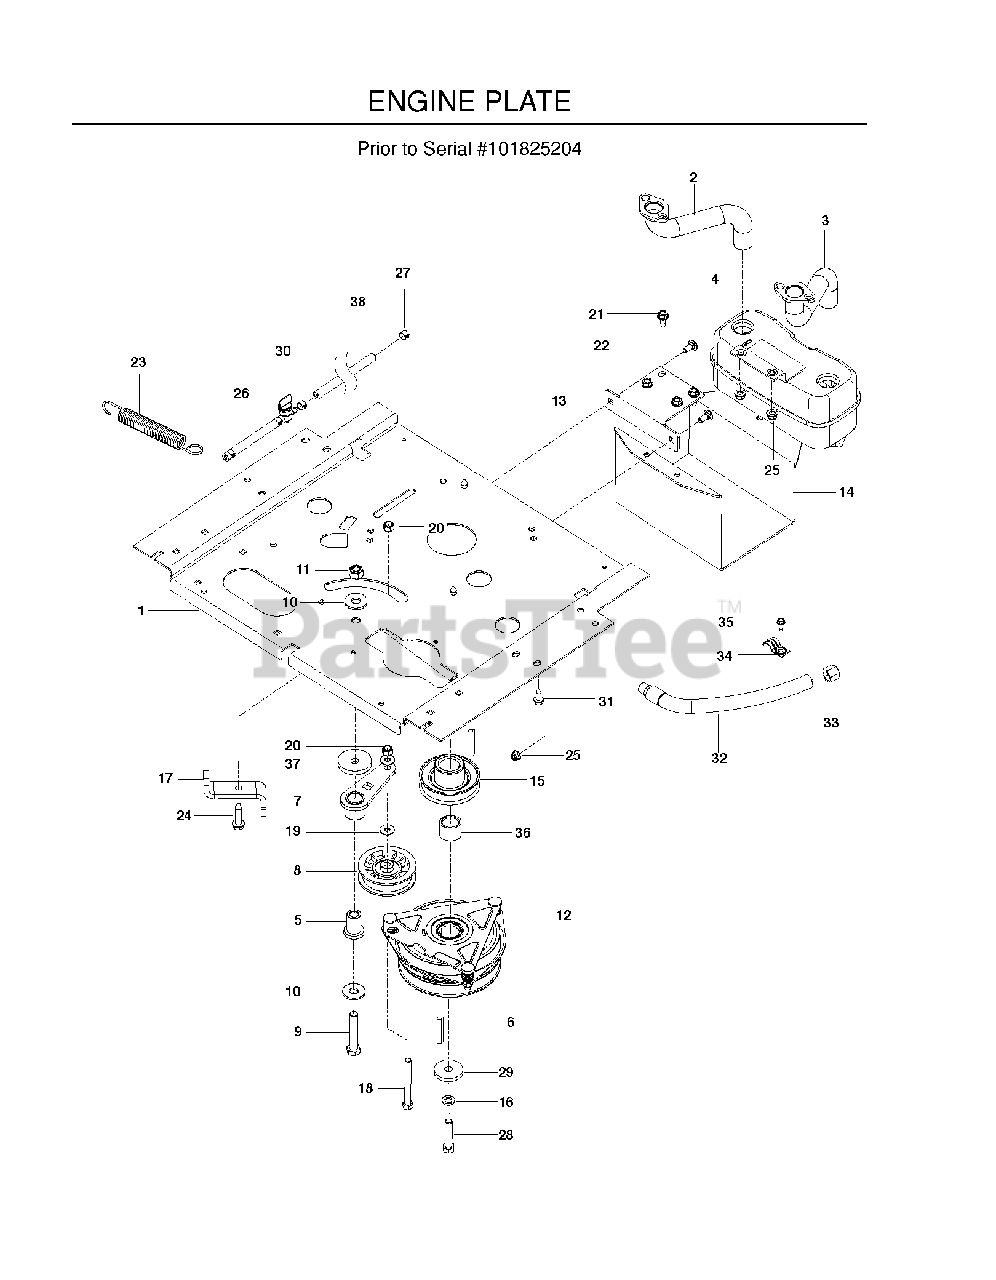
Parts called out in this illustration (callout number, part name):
1	PLATE, ENGINE WIDE, BLACK
2	RP.PIPE-EXHAUST LH
3	RP.PIPE-EXHAUST RH
4	MUFFLER ASM TWIN
5	PIVOT, IDLER
6	KEY, 1/4 SQ X 1 1/4
7	IDLER ARM WELDMENT
8	PULLEY, IDLER
9	HCS 1/2C X 2 3/4
10	WASH USS FLAT 1/2
11	NUT 1/2-13 HEX NYLOC ZD
12	CLUTCH, 150 FT/LBS
13	BRACKET, MUFFLER, BLACK
14	GUARD, MUFFLER, BLACK
15	PULLEY, C'SHAFT, 3.57 OP
16	WASHER 7/16 LOCK
17	STOP, CLUTCH BLK
18	HCS 3/8-16X3 1/2 GR5
19	WASHER 5/16 FLAT
20	NUT 3/8-16 NYLOC
21	BOLT 5/16-18 X 3/4
22	BOLT 5/16C X 3/4" CARRIAGE
23	SPRING, DECK DRIVE
24	BOLT 3/8-16 X 1 1/2 ZINC CLEAR
25	5/16-18 NYLOC FLANGE NUT
26	HOSE 1/4 X 8
27	HOSE CLAMP
28	HCS 7/16-20 X 2-3/4
29	SPINDLE WASHER
30	FUEL VALVE
31	HHFS 3/8-16 X 1.0 THD FORMING
32	OIL DRAIN HOSE
33	DRAIN CAP
35	SCREW 1/4 X 5/8
37	HEAVY WASHER
38	HOSE, FUEL .25 ID X 26"
